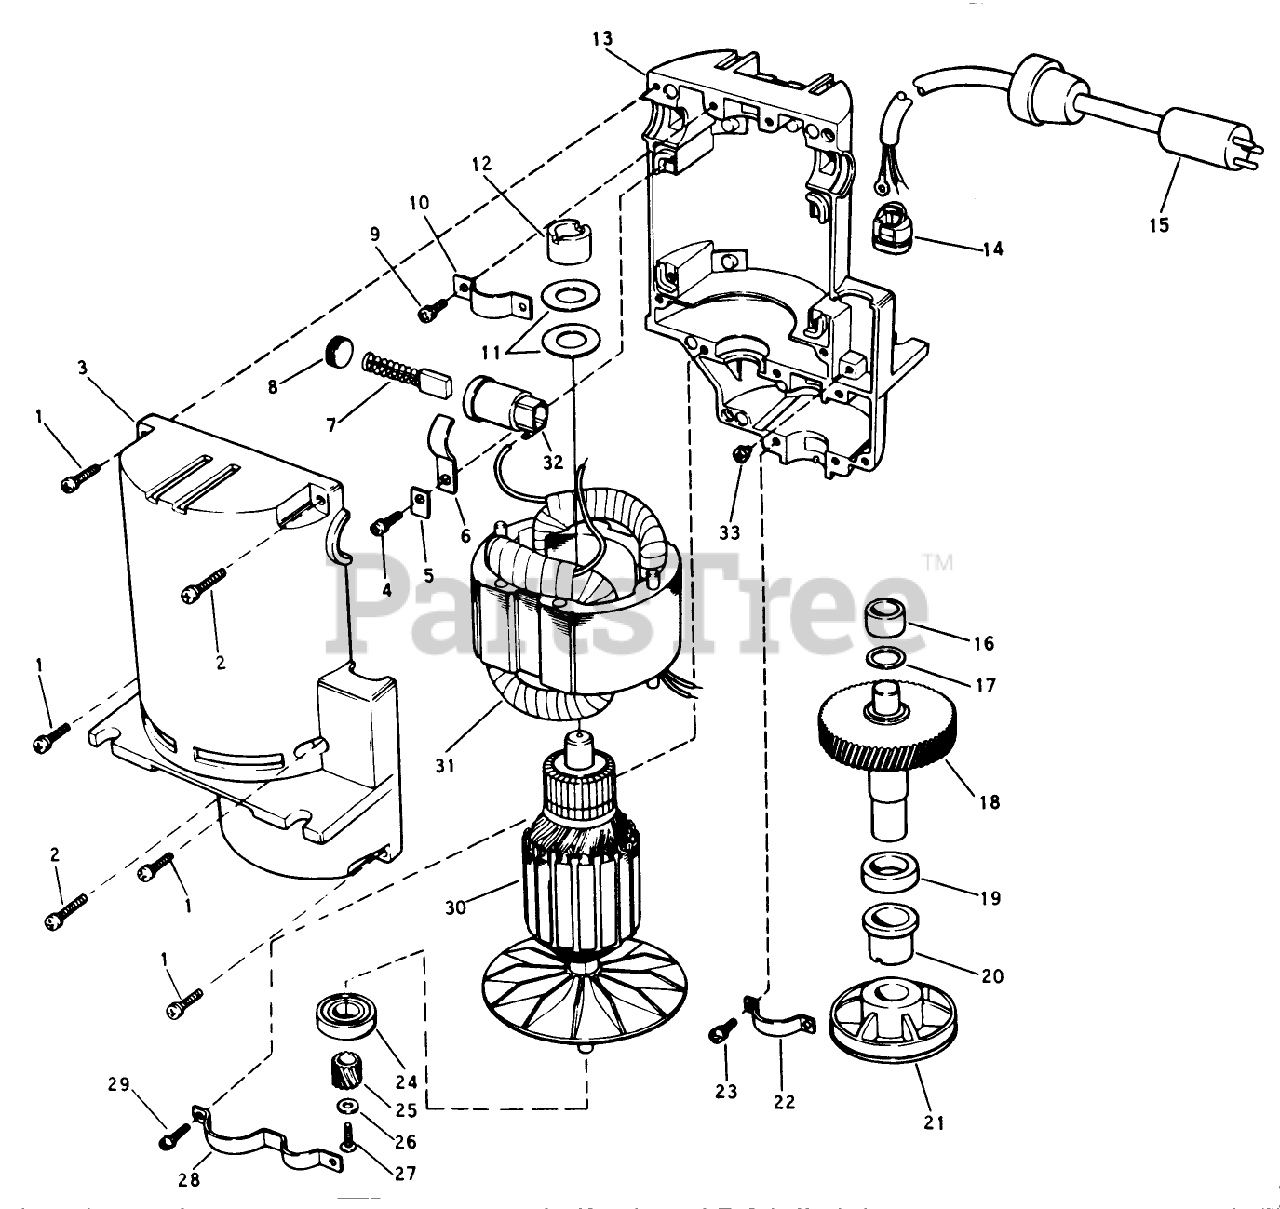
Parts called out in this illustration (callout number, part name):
1	Screw-Cover Casting
2	Screw-Cover Casting
3	Cover Casting-Motor
4	Screw-Bearing Clamp
5	Spacer-Brush Holder Clamp
6	Clamp-Brush Holder
9	Screw-Bearing Clamp
10	Clamp-Rear Armature Bearing
11	Washer-Fiber
12	Bearing-Armature-Rear
13	Main Casting-Motor
14	Strain Relief
16	Bushing
17	Washer-Spring Tension
18	Spindle Gear
19	Spacer-Spindle Gear
20	Bearing-Lower Spindle
22	Clamp-Brush Holder
23	Screw-Bearing Clamp
24	Bearing-Armature
25	Pinion-Armature
26	Washer-Pinion Screw
27	Screw-Pinion
28	Clamp-Armature Bearing
29	Screw-Bearing Clamp
30	Armature Assembly-L Pin
31	Field Assembly
32	Brush Holder
33	Screw-Ground Lead
